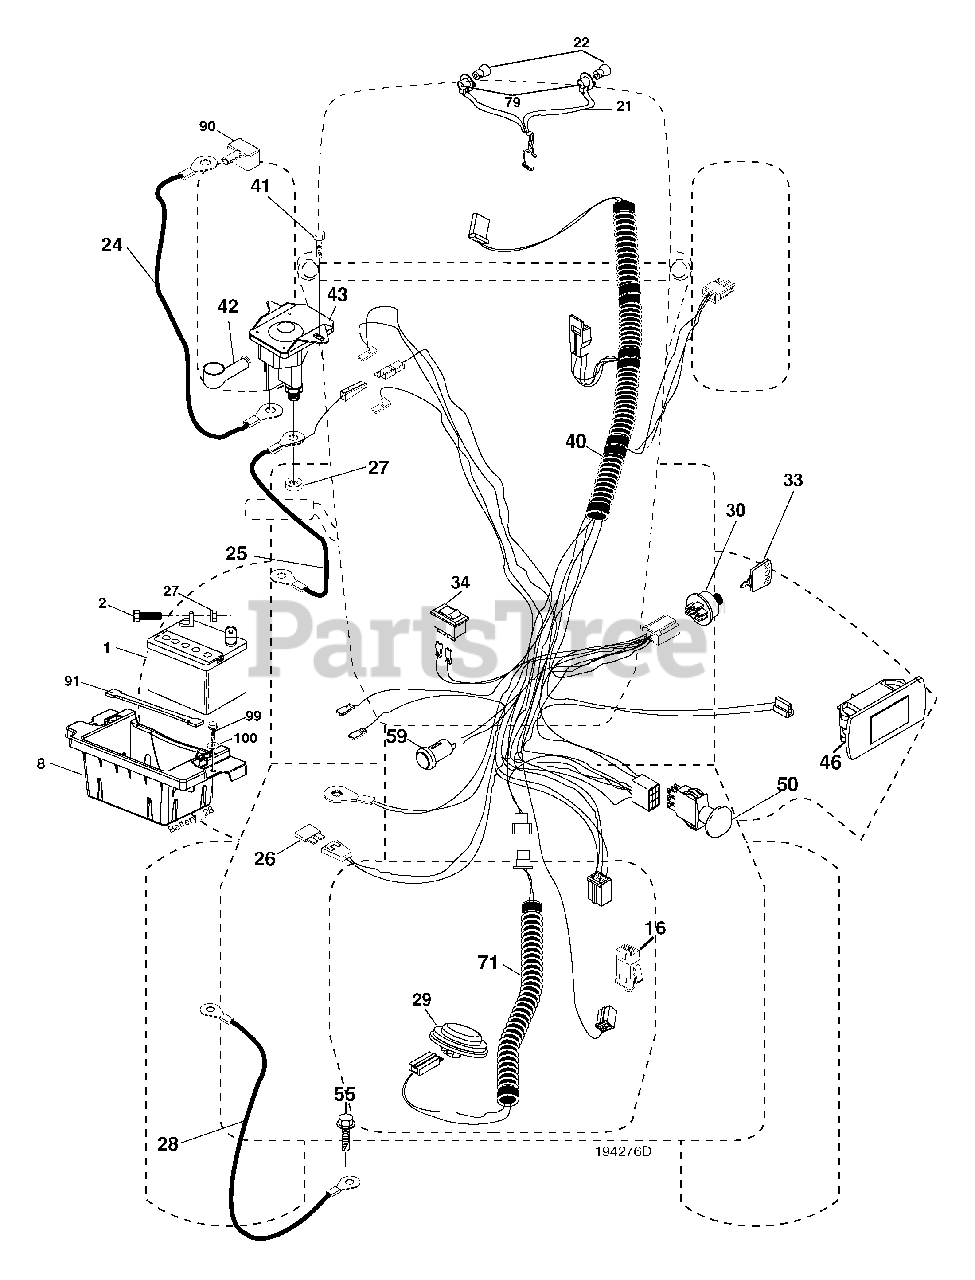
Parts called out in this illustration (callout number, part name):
1	Battery
2	Bolt Hex Head 1/4-20 x 3/4
8	Box Battery
16	Switch Interlock Push-In
21	Harness Socket Light W/4152J
22	Bulb Light
24	Cable Battery
25	Cable Start Red 17.5"
26	Fuse
27	Nut Keps Hex 1/4-20 unc
28	Cable, Ground
29	Switch, Seat
30	Switch, Ignition
33	Key, Ignition
34	Switch Light / Reset
40	Harness Ignition
41	Screw Thd Cut 1/4-20 x 1/2
42	Cover, Terminal
43	Solenoid
46	Gauge Hourmeter
50	Switch, PTO
55	Screw Thdrol 5/16-18 x 3/4 TYTT
59	Outlet 12-Volt
71	Harness Ign. Dash
79	Bulbholder Asm. Incan Descent
90	Cover Terminal Battery
91	Strap Battery Mount Front
99	Screw Hexwsh Thdrol 1/4-20 x 3/4
100	Washer 9/32 x 7/8 x 16 Ga.
